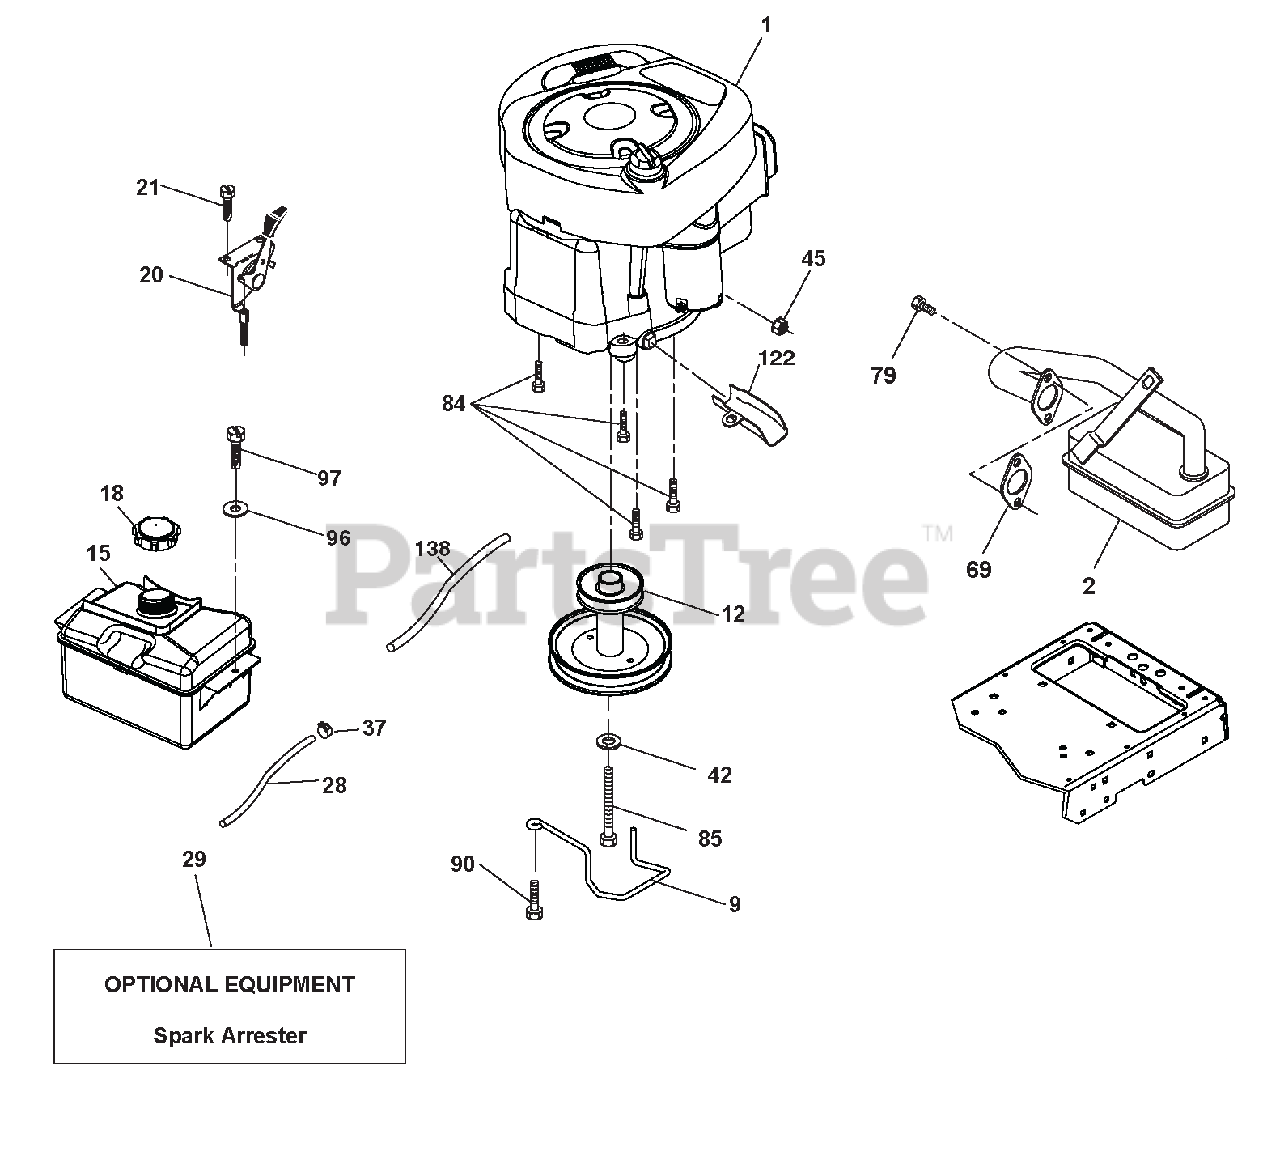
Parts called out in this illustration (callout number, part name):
1	ENGINE BRIGGS MODEL NO. 219807-3389-G5 (438203) (ORDER PARTS FROM ENGINE MANUFACTURER.)
2	MUFFLER
9	KEEPER BELT ENGINE
15	TANK FUEL
18	CAP FUEL
20	CONTROL.THROTTLE
28	LINE.FUEL.22"FRONT.EMIS.CA.LP
29	KIT.SPARK ARRESTOR(392390 B&S)
37	CLAMP.HOSE.BLK.
42	WASHER.LOCK.HVY HLCL.SPR.7/16
45	Nut, Keps Hex 1/4-20 unc
69	Gasket Eng 1 313 Id Tin Plated
79	SCREW.SOCKET HD.5/16-18 X .75
84	Screw 3/8-16 x <
85	BOLT.HEX.7/16-20X4XGR5-1.5THR.
90	SCREW.3/8-16X1.SMGML.TAP/R.BLK
96	WASHER.9/32 X 7/8 X 16GA.
97	SCREW.HEXWSH.THDROL.1/4-20X3/4
122	Extension Drain Oil
138	PURGE.LINE.CARB
